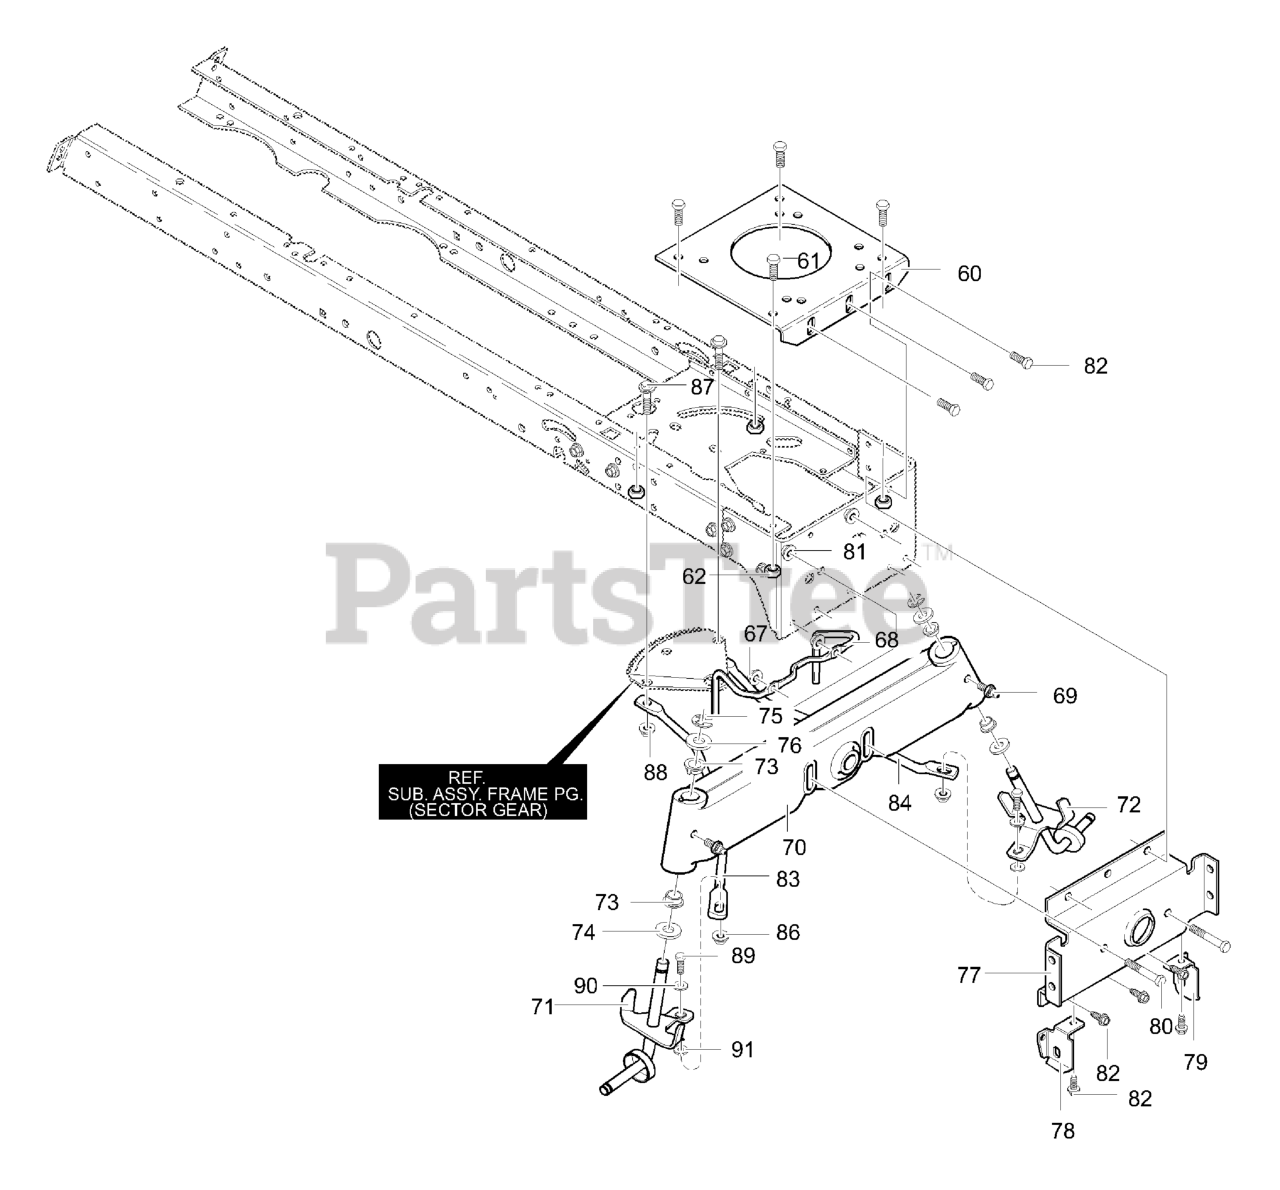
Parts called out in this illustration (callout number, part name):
60	Engine Plate
61	Screw, .312-18x.75
62	Nut, 5/16-18
67	Nut, 5/16-18
68	Guide-Stack Pulley Belt
69	Zerk, Grease
70	Axle, Cast Machined
71	Spindle, Long RH
72	Spindle, Long LH
73	Bearing, Spindle
74	Washer, .766IDx1.62ID
76	Washer, Flat
77	Hanger, Axle
78	Hanger, Deck RH
79	Hanger, Deck LH
80	Screw, 5/16-18 x 3.00
81	Nut, 5/16-18
82	Screw, .312-18x.75
83	Drag Link, RH
84	Drag Link, LH
86	Nut, 3/8-16
87	Shoulder Bolt
88	Nut, 3/8-16
89	Screw, 3/8-16 x 1.50
90	Flatwasher
91	Flatwasher
